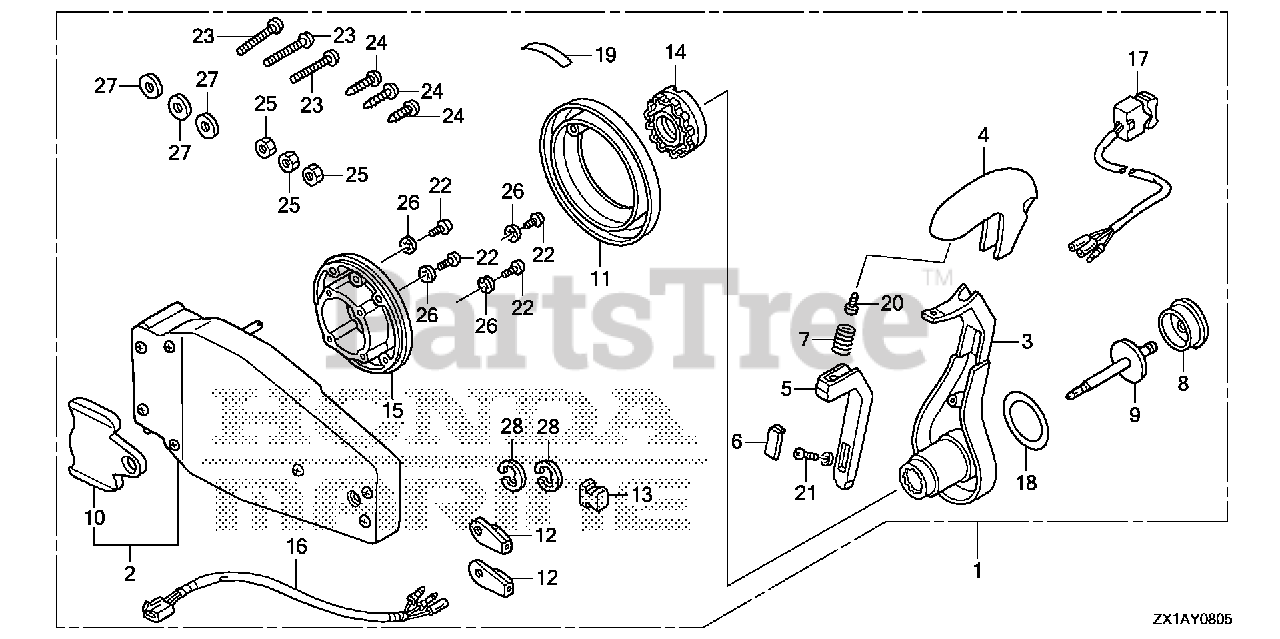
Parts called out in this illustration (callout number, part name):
1	BOX KIT, REMOTE CONTROL (FLUSH MOUNT)(L)
2	HOUSING ASSY., L. (INNER) (FLUSH MOUNT)
3	HANDLE, REMOTE CONTROL
4	COVER, GRIP
5	ARM, NEUTRAL LOCK
6	COVER, LOCK ARM
7	SPRING, NEUTRAL LOCK ARM
8	BUTTON, THROTTLE
9	SHAFT, THROTTLE BUTTON
10	PLATE, DWELL
11	COVER ASSY.
12	TERMINAL, CABLE
13	SPACER, CABLE CLAMP
14	HOLDER, NEUTRAL LOCK
15	BASE
16	SUB-HARNESS ASSY., POWER TRIM-TILT (C)
17	SWITCH ASSY., POWER TRIM-TILT (C)
18	MARK, HANDLE FLUSH MOUNT
19	MARK, FLUSH MOUNT
20	SCREW, PAN (5X16)
21	SCREW, TRUSS (4X12)
22	SCREW, PAN (5X30)
23	SCREW, PAN (6X35)
24	SCREW, TAPPING (6X30)
25	NUT, HEX. (6MM)
26	WASHER, LOCK (5MM)
27	WASHER, PLAIN (6MM)
28	E-RING (6MM)
